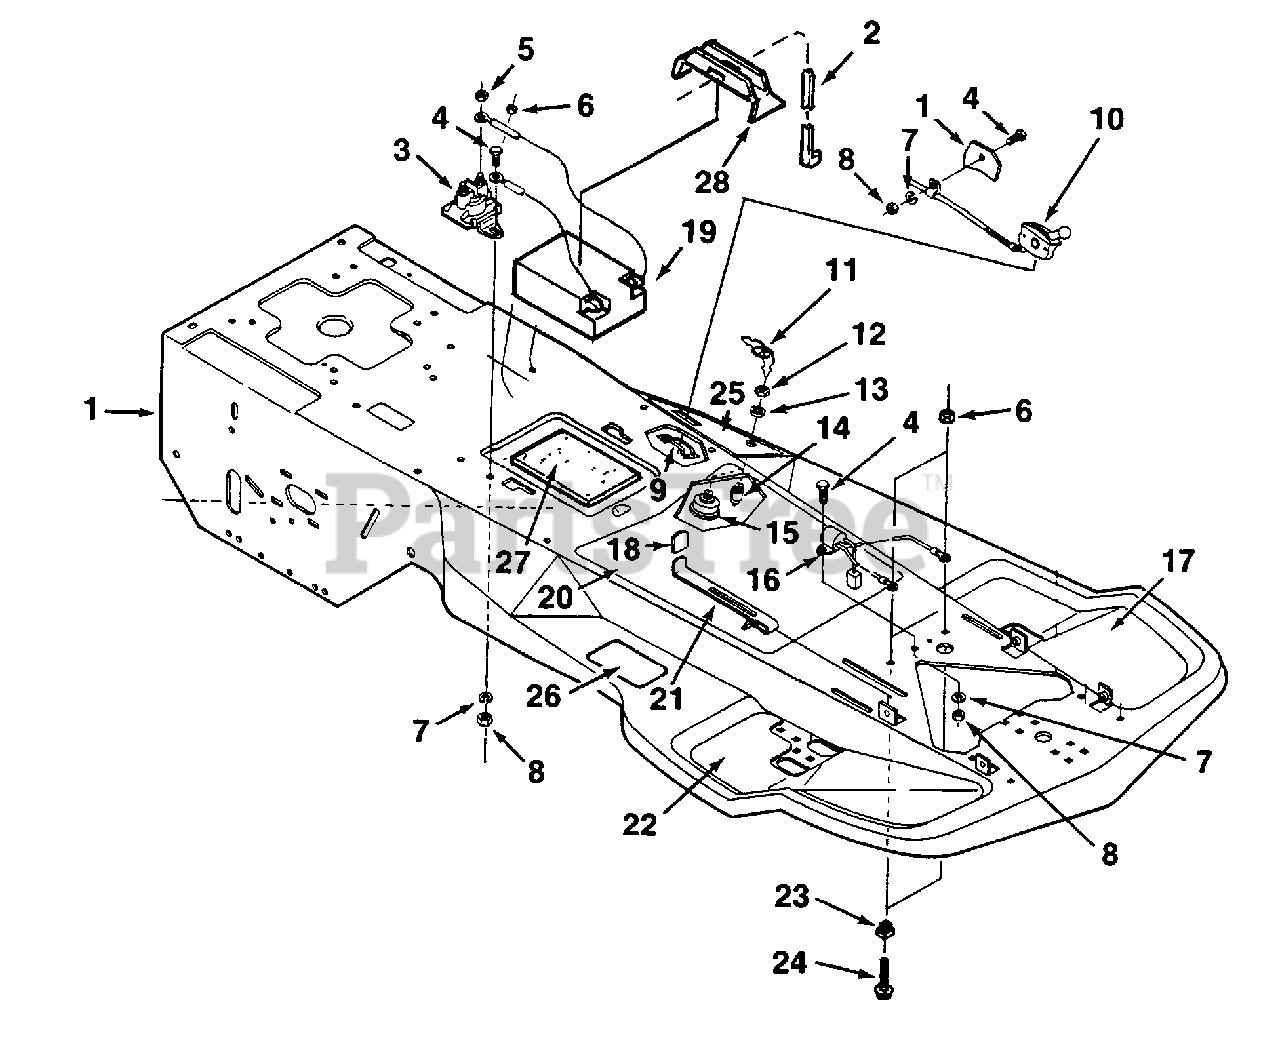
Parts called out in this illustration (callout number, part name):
1	FRAME-RMX
2	STRAP- Self locking
3	SOLENOID
4	SCREW
5	NUT
6	NUT
8	NUT
14	SWITCH- Ignition
15	SWITCH
16	MODULE- Safety
17	PAD- Foot rest L.H.
19	BATTERY
21	LATCH- Brake
22	PAD- Foot rest R.H.
25	DECAL-
26	PAD- Foot
27	PAD- Battery
28	BRACKET- Battery
